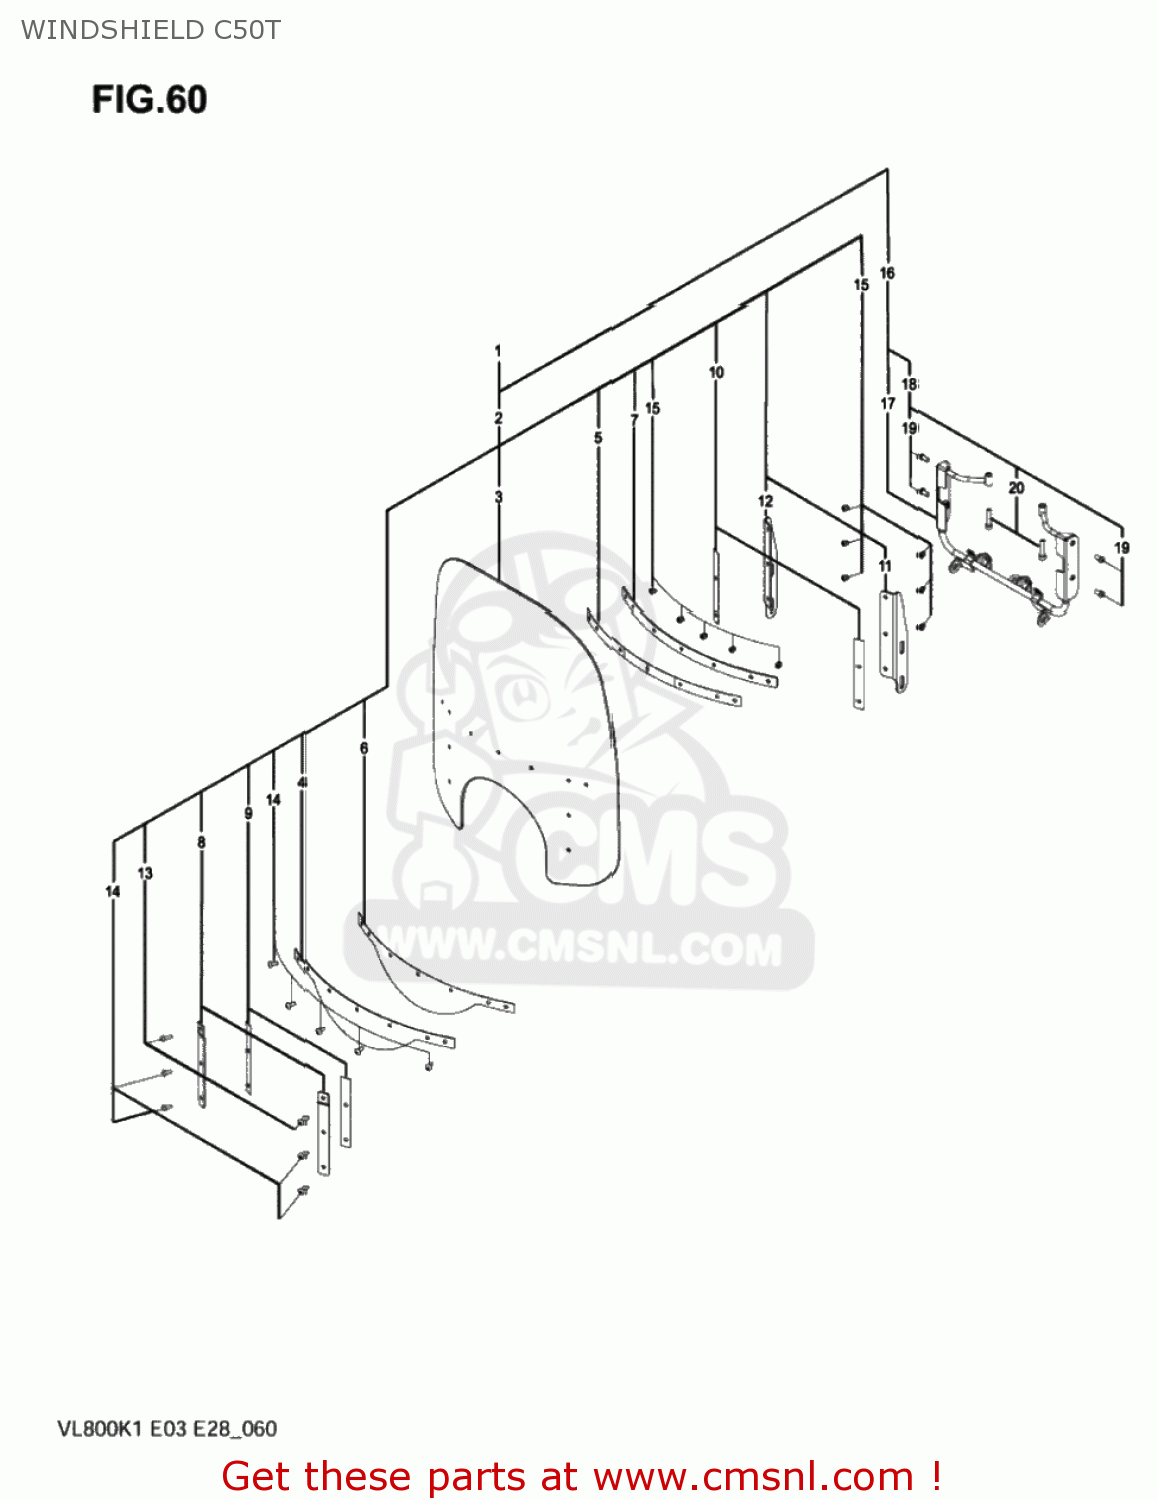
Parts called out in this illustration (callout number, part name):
1	C50T CLASSIC WN
3	C50VL8 WINDSHLD
4	OUTSIDE PLATE,HORIZONTAL
5	GASKET,HORIZONTAL (NAS)
6	GASKET,HORIZONTAL (NAS)
7	INSIDE STRIP,HORIZONTAL
8	C50 WSHLD OUTR
9	GASKET,VERT,OUTSIDE STRIP (NAS)
10	GASKET,VERT,INSIDE STRIP (NAS)
11	BRACKET,FRAME,VERT,LH
12	BRACKET,FRAME,VERT,RH
13	CAP SCREW M6-1.0X20,SS,
14	CAP SCREW M6-1.0X16,SS,
15	NUT,HEX CAP, M6-1.0 88
16	HARDWARE KIT,C50T WINDSHIELD
17	BRACE,COMPLETE,WINDSHIELD
19	CAP SCREW M8-1.25X16,SS
20	CAP SCREW M8-1.25X40,SS
